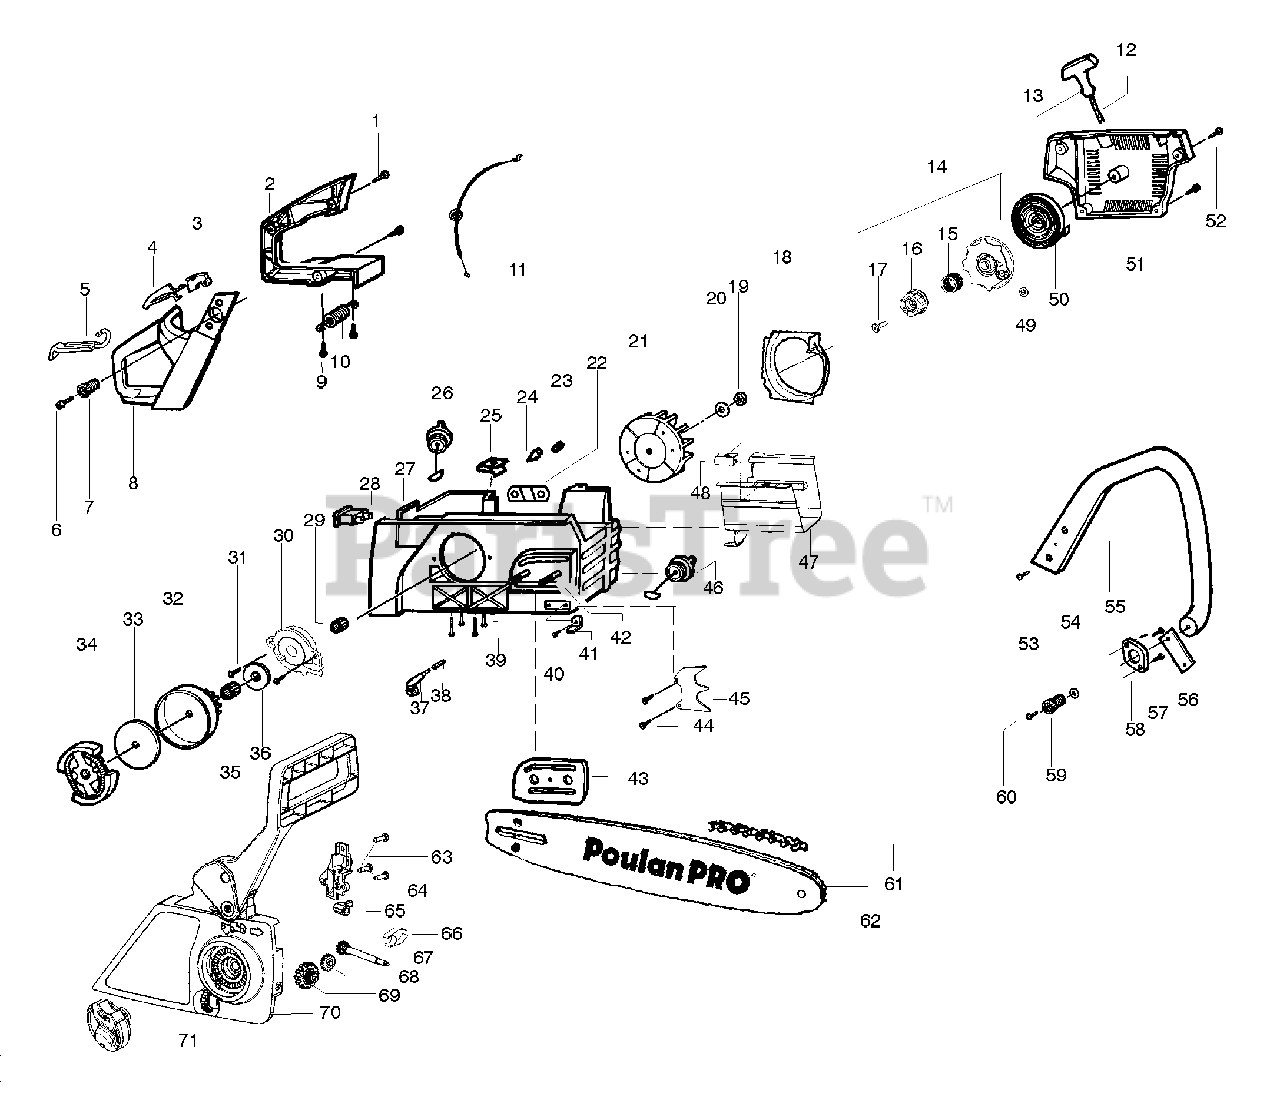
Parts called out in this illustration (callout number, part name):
2	Cover-Handle
3	Trigger-Throttle
4	Lockout-Throttle
5	Lever-Choke
7	Spring-Isolator
8	Handle-Rear
10	Spring-Isolator
11	Assy-Throttle Cable
12	Kit-Rope
13	Handle-Starter
14	Kit-Starter EPS
15	Spring EPS
16	Hub-Starter EPS
17	Screw-Shoulder
18	Plate-Baffle Fan
19	Nut-Flywheel
20	Washer-Flywheel
21	Assy-Flywheel
22	Plate-Support
23	Plug-Vent
24	Valve-Check
25	Nut-Speed
26	Assy-Fuel Cap
27	Assy-Chassis
28	Kit-Switch
29	Worm-Oil Pump
30	Assy.-Oil Pump
32	Kit-Clutch Drum
33	Washer-Clutch
34	Assy-Clutch
35	Bearing-Clutch
36	Washer-Thrust
37	Pickup-Oil
38	Filter-Oil
41	Chain Catcher
42	Bar Bolt
43	Bar Plate
45	Kit-Spike Assy
46	Assy-Oil Cap
47	Shield-Heat
48	Clip-"U"
50	Spring-Recoil
51	Housing-Fan
54	Washer
55	Handle-Front
56	Front Strap-AV
57	Screw-Plate
58	Plate-Isolator
59	Spring-Isolator
61	Chain"- 20"
62	Bar -20"
64	Cover-Gear
65	Pin-Bar Adjust
66	Clip-Spring
67	Screw-Adjuster
68	Gear-Idler
69	Wheel-Gear Adjust
70	Kit -ChainBrake Assy.
71	Kit - EZ T Knob
